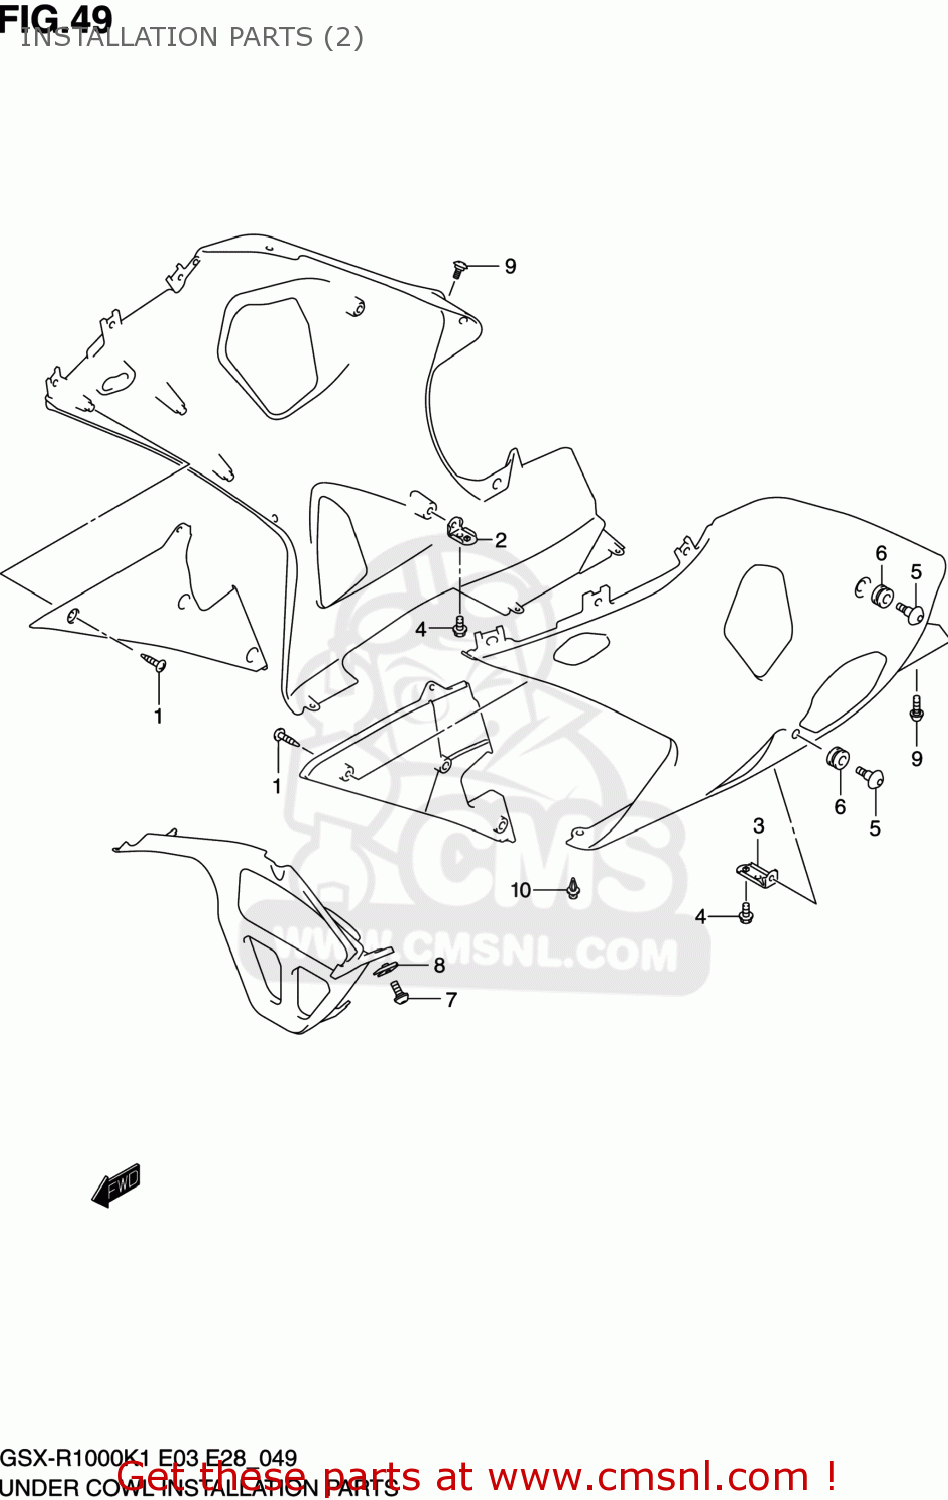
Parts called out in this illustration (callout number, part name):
1	SCREW
2	BRACKET,UNDER COWLING LWR,R
3	BRACKET,UNDER COWLING LWR,L
4	BOLT
5	SCREW(6X20)
6	CUSHION
7	SCREW(5X13)
8	NUT,COWL
9	SCREW(5X13)
10	CLIP
